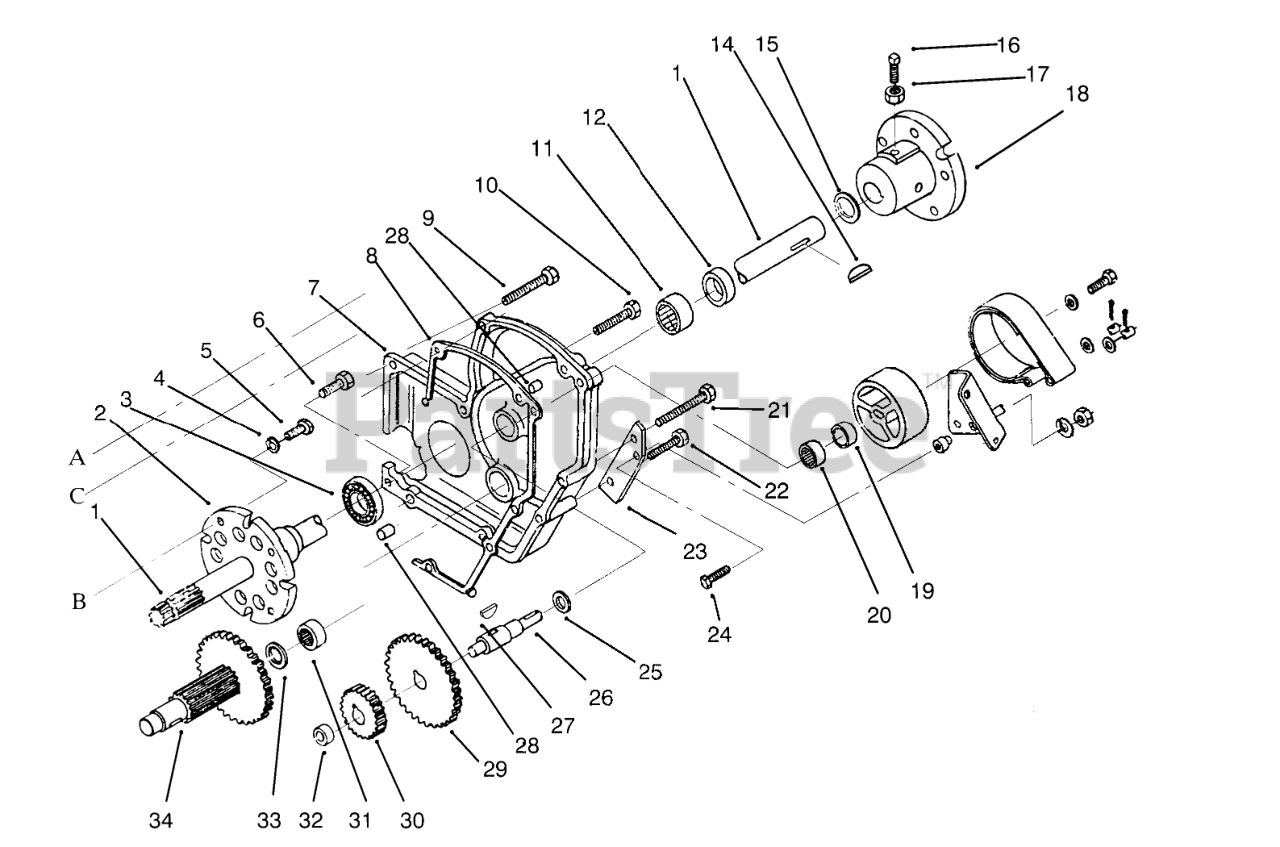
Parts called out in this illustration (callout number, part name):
1	AXLE-REAR LH
2	END CAP-DIFFERENTIAL
3	BEARING-BALL
4	WASHER
5	BOLT-HEX
7	CASE TRANS LH
8	GASKET-TRANSMISSION
9	SCREW-HH
11	BEARING
12	SEAL-OIL
14	KEY-WOODRUFF
15	WASHER-THRUST
16	SCREW-SET, SQH
17	NUT-JAM
18	Hub Rear
19	Seal
20	NEEDLE BEARING
21	SCREW-HH
22	SCREW-HH
23	BRACKET-BRAKEB
24	SCREW-HH
25	Race Thrust
26	SHAFT GEAR
27	Key
28	PIN-LOCATING
29	GEAR 46 TEETH
30	GEAR 20 TEETH
31	BEARING-NEEDLE
32	BEARING-NEEDLE
33	WASHER-THRUST
34	ASSY GEAR
